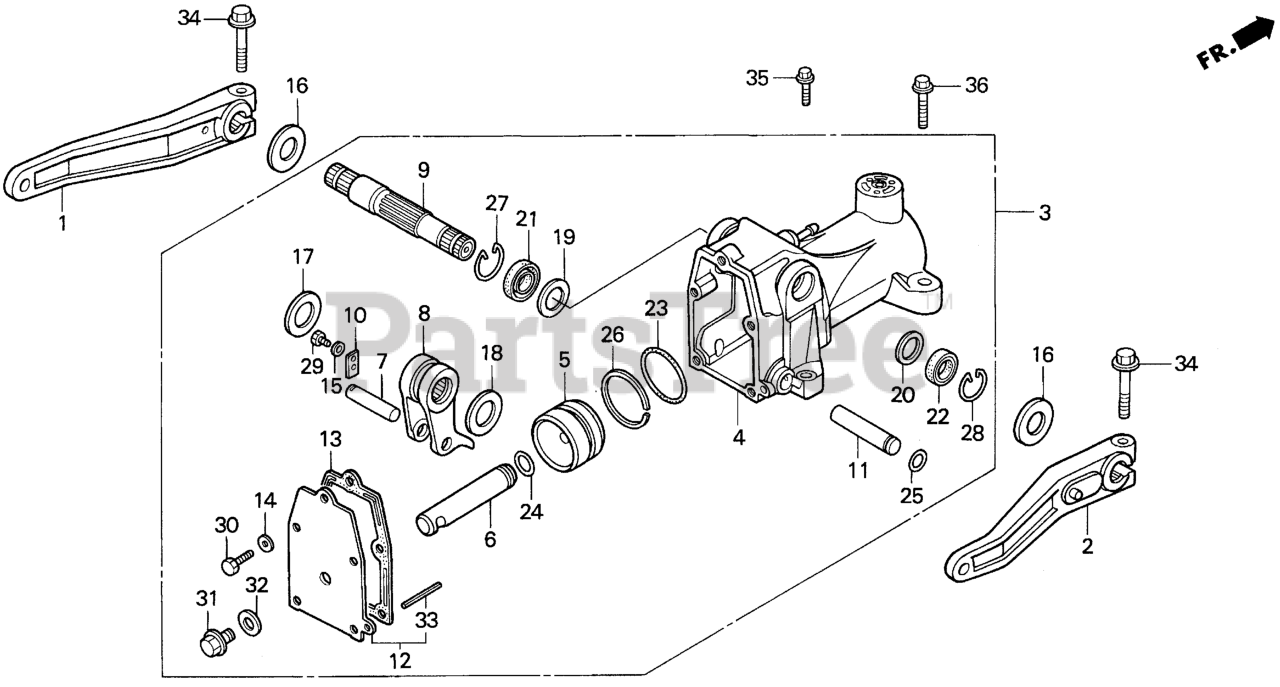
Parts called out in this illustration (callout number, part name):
1	ARM, L. RR. LIFT
2	ARM, R. RR. LIFT
3	CYLINDER ASSY., HYDRAULIC Use up to Frame SN 2500167.
4	CYLINDER, HYDRAULIC
5	PISTON, HYDRAULIC (60MM)
6	ROD, CONNECTING
7	PIN, CONNECTING ROD
8	ARM, HYDRAULIC CYLINDER
9	SHAFT, HYDRAULIC CYLINDER
10	PLATE, CONNECTING ROD PIN
11	SHAFT, STOPPER
12	COVER, CYLINDER
13	GASKET, HYDRAULIC CYLINDER COVER
14	WASHER (8MM)
15	WASHER, CONICAL SPRING (6MM) Use up to Frame SN 3500085.
16	WASHER, THRUST (25.5X50X5)
17	WASHER, PLAIN (INNER) (28.5MM)
18	WASHER, PLAIN (INNER) (25.5MM)
19	WASHER, PLAIN (OUTER) (30.5MM)
20	WASHER, PLAIN (OUTER) (25.5MM)
21	OIL SEAL (30X44X8)
22	OIL SEAL (25X38X9)
23	O-RING, HYDRAULIC CYLINDER
24	O-RING (17X3.5)
25	O-RING (13.8X2.4) (NOK)
26	RING, BACK-UP
27	RING, STOPPER (49)
28	RING, STOPPER (43)
29	BOLT, HEX. (6X12)
30	BOLT, HEX. (8X22)
31	BOLT, DRAIN PLUG (14MM)
32	WASHER, DRAIN PLUG (14MM)
33	PIN, SPRING (6X40)
34	BOLT, FLANGE (10X40)
35	BOLT, FLANGE (10X55)
36	BOLT, FLANGE (12X50)
